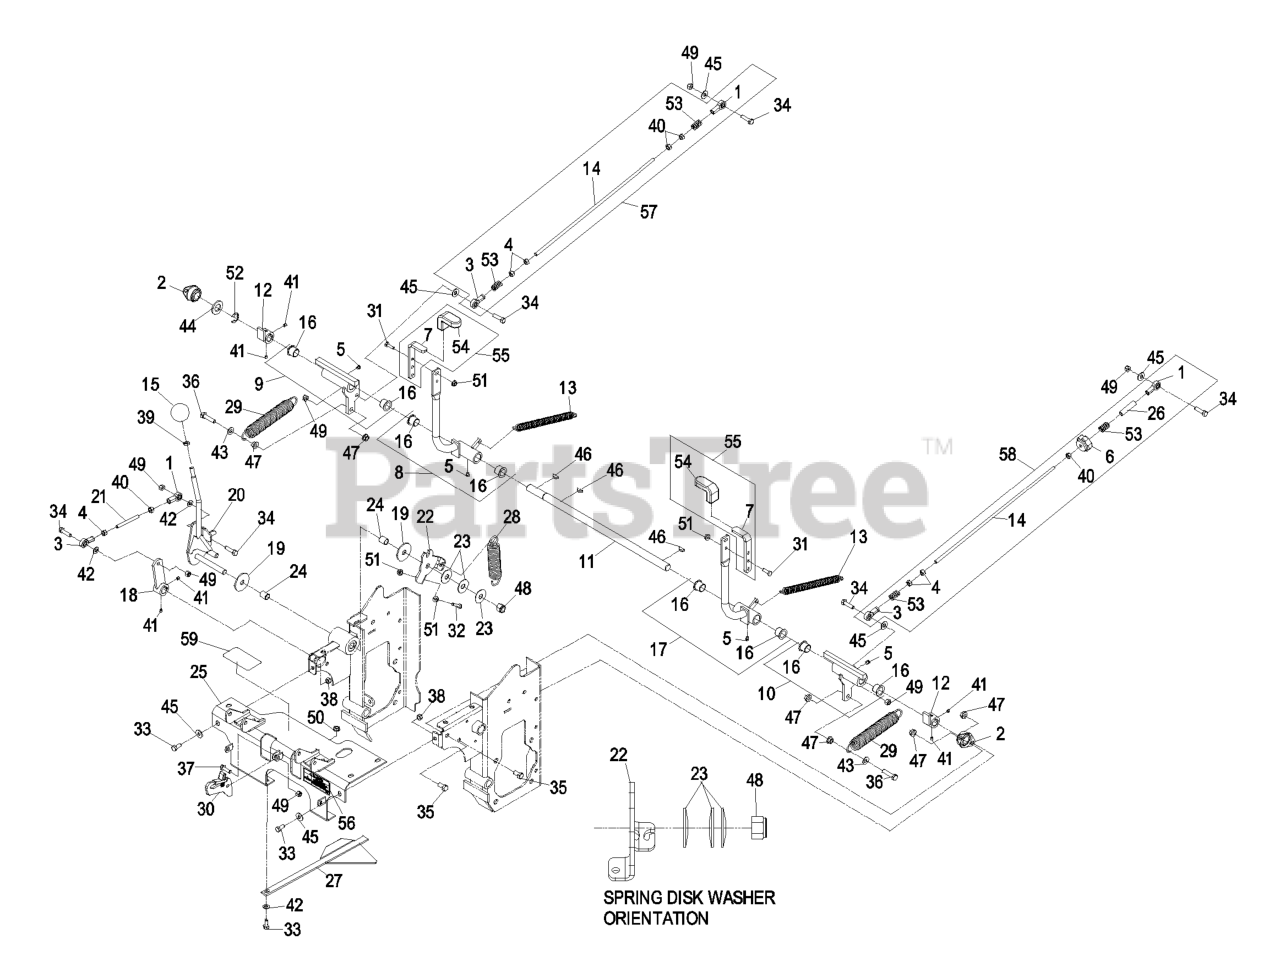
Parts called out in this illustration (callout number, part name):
1	BALLJOINT-RH
2	BEARING-FLANGE, SIDE
3	BALLJOINT-LH
4	NUT
6	KNOB-TRACKING
7	ASM,HANDLE W/GRIP
8	ASM,STEERING LEVER RH W/B
9	ASM,ACTUATOR RH W/BEARING
10	ASM,ACTUATOR LH W/BEARING
11	SHAFT,SPEED CONTROL
12	WLD,HUB SPEED CONTROL
13	SPRING,EXTENSION
14	LINKAGE,ROD LH STEERING (
15	KNOB-BALL, SPEED CONTROL
16	BEARING-FLANGE, IGLIDE
17	ASM,STEERING LEVER LH W/B
18	WLD,CONTROL ARM (PLATED)
19	DISC-FRICTION
20	WLD,SPEED CONTROL LEVER(P
21	ROD,THREADED CONTROL LINK
22	PLATE,SPEED CONTROL FRICT
23	WASHER-DISC, SPRING
24	BEARING,PLASTIC 1/2"
25	Asm, Console W/Decals
27	GUIDE-PLENUM
28	SPRING,EXTENSION (PLATED)
29	SPRING-EXTENSION
31	SCREW-HH
32	SCREW-HH
33	SCREW-HH
34	SCREW-HH
35	SCREW-HH
36	SCREW-HH
37	SCREW-HH
38	NUT-HEX
39	NUT-JAM
40	NUT-HEX
41	SCREW-SET, HSH
42	WASHER-PLAIN
43	WASHER-FLAT
44	WASHER-FLAT
45	WASHER-FLAT
46	KEY-WOODRUFF
47	NUT-HHF, WHIZ
48	NUT-HEX
49	NUT-LOCK, NI
53	SPRING-COMPRESSION
54	GRIP-HANDLE, STEERING
55	ASM,HANDLE W/GRIP
56	DECAL-DRIVELINE
57	ASM,RH PUMP LINKAGE
58	ASM,LH PUMP LINKAGE
59	DECAL,WHEEL MOTOR RELEASE
